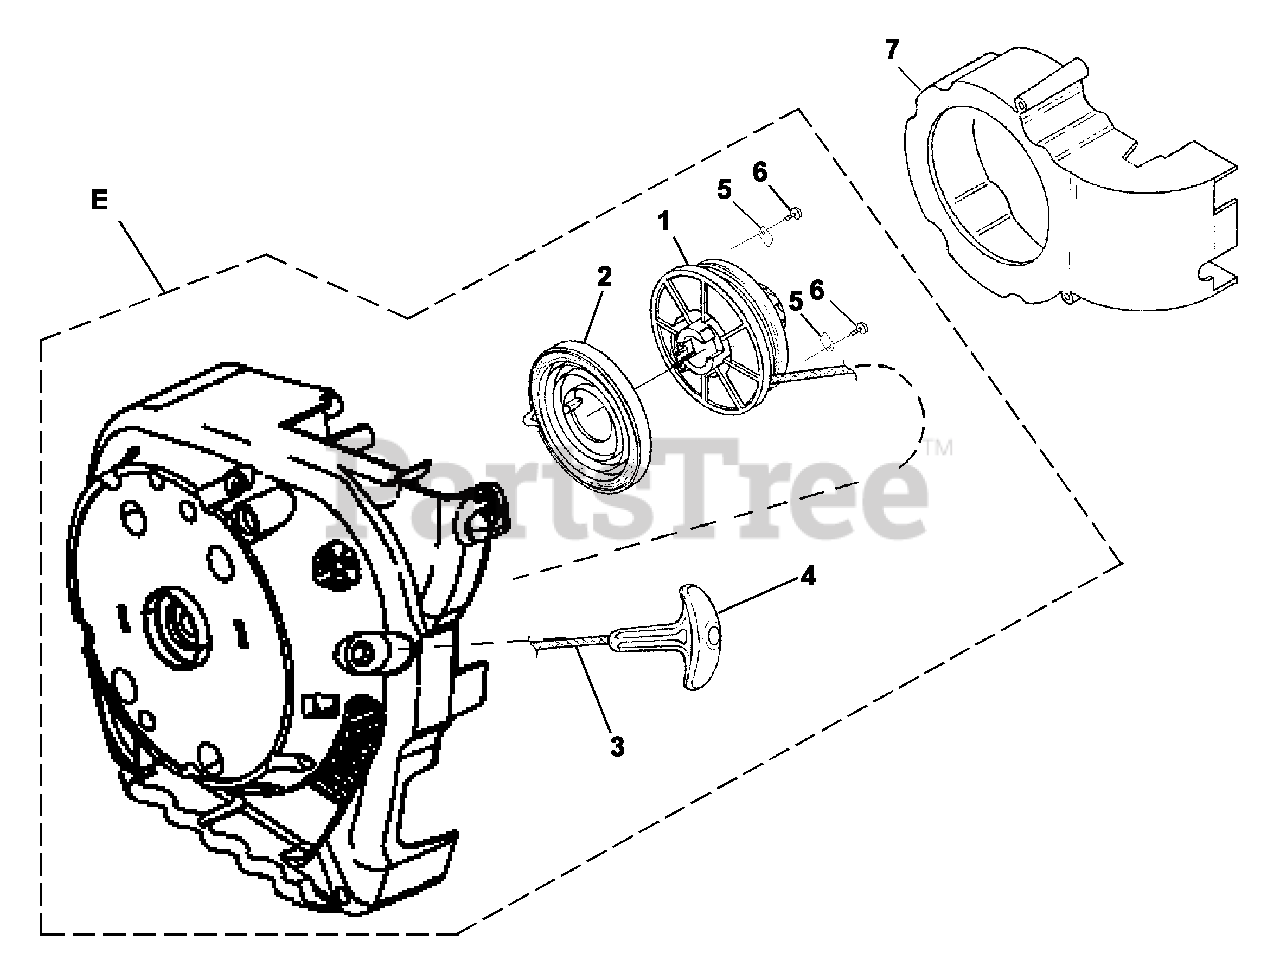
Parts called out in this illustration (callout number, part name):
1	Pulley, Starter
2	Spring & Container
3	Rope, Starter 42"
4	Grip, Starter
5	Bracket-Retaining
6	Screw-Plastite (#10-1/2")
7	Scroll
E	Starter (Svc)
